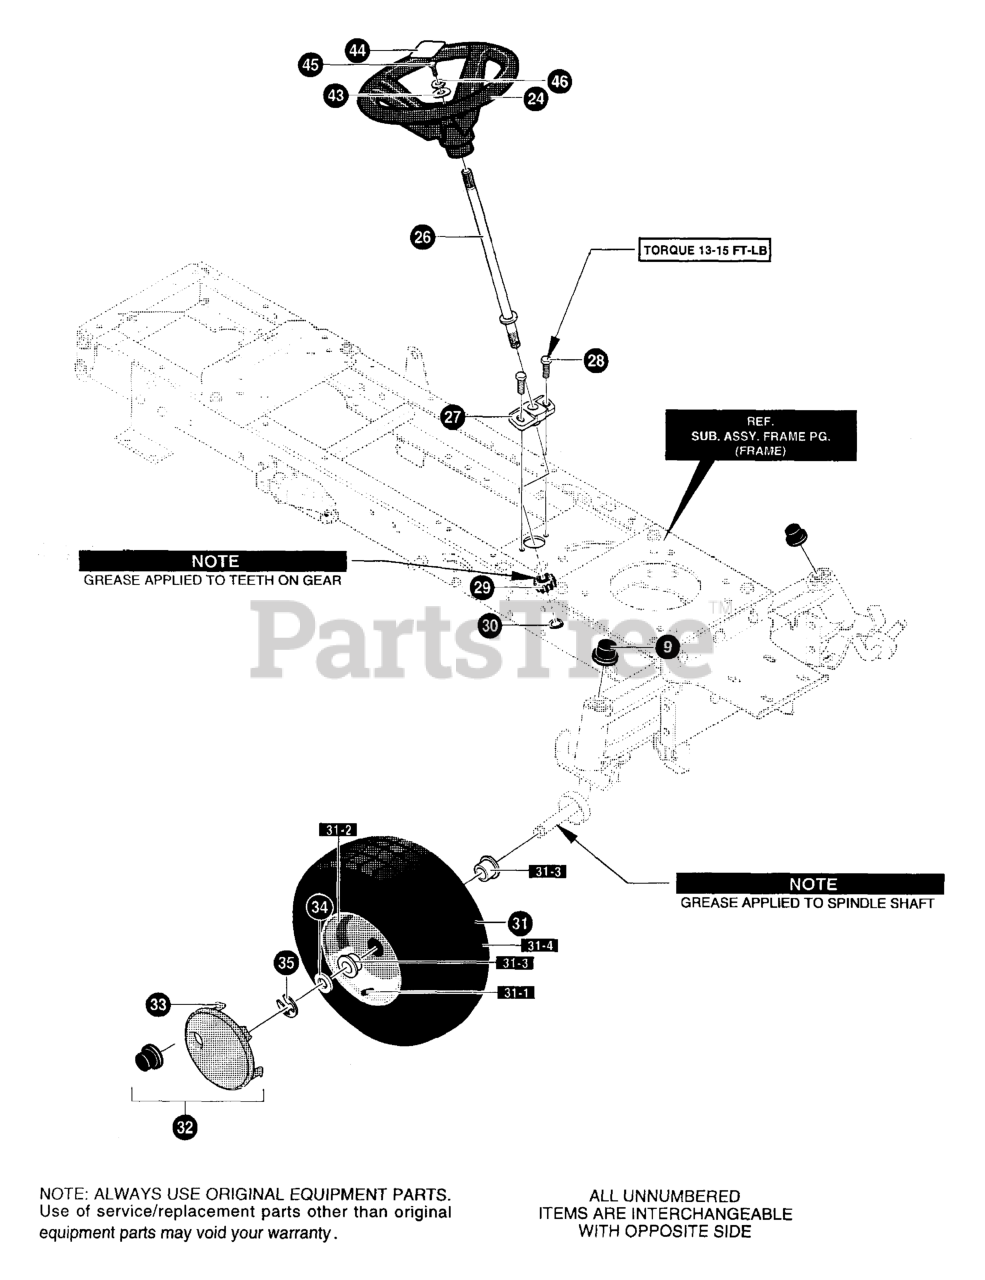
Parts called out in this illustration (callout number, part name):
9	HUB CAP
24	STEERING WHEEL
26	SHAFT, STEERING
27	BEARING-LOWER
28	SCREW, 5/16-18 x 0.75 HHWATAPSGIBP
29	GEAR PINNION
30	RING, RET E.54ID .59SH (11X25)
31	TIRE & RIM 15X6-6
31-1	VALVE STEM
31-2	RIM, CARLISLE
31-3	BEARING
31-4	TIRE, 15X6X6
32	HUB CAP, W/O HOLE
33	CLIP, HUBCAP TINN
34	WASHER, FLAT,.765X1.81X.059
35	"E" RING .574 IDX.050/.750SH 11X3
43	FLATWASHER.281X1.25X.06
44	INSERT, STEERING WHEEL
45	SCREW, 1/4-20X.75
46	WASHER (18x32)
